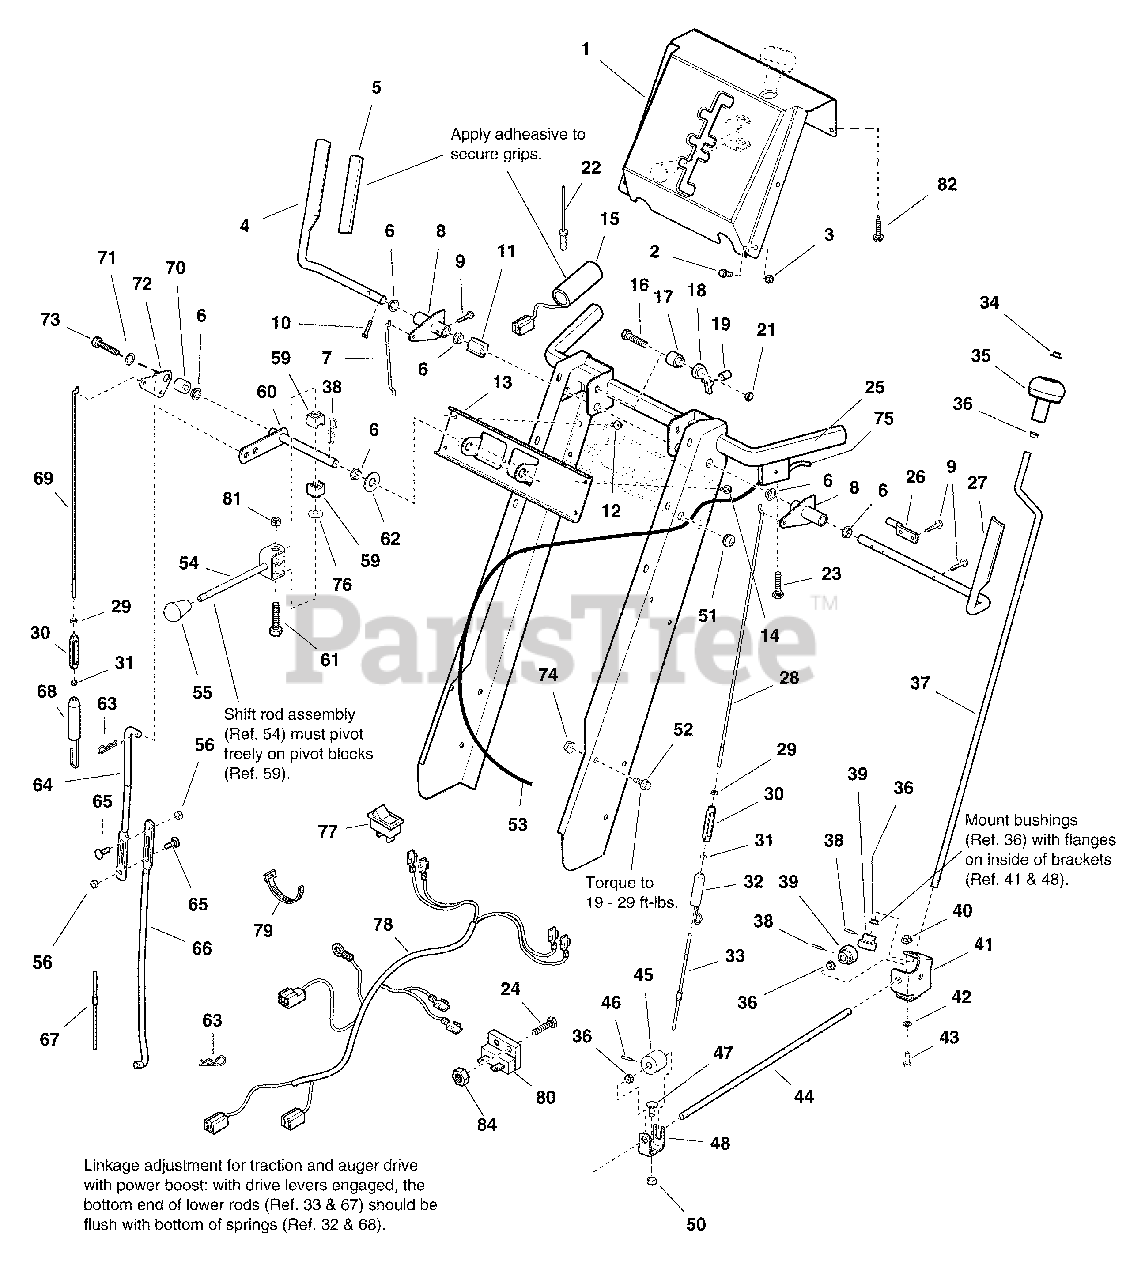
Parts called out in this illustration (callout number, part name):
2	CAPSCREW, Hex Head, 1/4-20 x 3/4
3	NUT, Whiz Lock 1/4-20
4	HANDLE, Clutch, RH
6	BUSHING, Nylon
7	ROD, Clutch
8	LEVER & TUBE ASSEMBLY
9	CAPSCREW, Hex Washer Head, #12-24 x 1
10	CAPSCREW, Hex Washer Head, #10-24 x 1
11	GUIDE, Control
12	SCREW, Hex Washer Head Taptite 1/4-20 x 3/4
13	BRACKET, Shift Control
14	SCREW, Hex Washer Head Taptite 1/4-20 x 3/4
15	HAND GRIP, Heated
16	SCREW, Hex Whiz Lock Flange 5/16-18 x 1 1/2, Black
17	SPACER
18	LATCH, Control
19	SPRING, Compression
21	NUT, Hex ESNA 5/16-18, Black
23	SCREW, Pan Torx Head, #10 x 1/2
24	CAPSCREW, Hex Head, 1/4-20 x 3/4
25	HANDLE ASSEMBLY
26	ROD, Control
27	HANDLE, Clutch, LH
28	ROD, 17.3" Long
29	NUT, LH, Machine Screw, Hex, #10-24
31	NUT, RH, Machine Screw, Hex, #10-24
33	ROD, Clutch
34	PUSH NUT
35	KNOB, Spinner
36	BUSHING, Nylon
37	ROD, Chute Control
38	PIN, Hair
40	NUT, Hex Flange, 1/4-20
41	SUPPORT, Gear
42	PUSH NUT
43	CARRIAGE BOLT, 1/4-20 x 5/8
46	PIN, Spring, 1/8 x 3/4
47	CARRIAGE BOLT, 5/16-18 x 3/4
48	SUPPORT, Worm
50	NUT, Hex ESNA, 5/16-18, Black
52	CAPSCREW, Hex Whiz Lock, 5/16-18 x 3/4
53	CABLE & HANDLE ASSEMBLY, Clutch (Includes Ref. 75)
54	SHIFT ASSEMBLY, Rod & Clevis
56	NUT, Hex KEPS, 1/4-20, Black
59	BLOCK, Pivot
60	ROD & ARM ASSEMBLY, Pivot
61	CAPSCREW, Hex Head, 1/4-20 x 2 1/4, Black
62	WASHER, 1/2
63	PIN, Hair
64	ROD, Shift, Upper
65	CARRIAGE BOLT, 1/4-20 x 3/4
66	ROD, Shift, Lower
67	ROD, Clutch, Lower
69	ROD, Clutch, Upper
71	WASHER, Plain 11/32 x 3/4 x 1/16
72	LEVER, Clutch
73	CAPSCREW, Hex Whiz Lock Flange 5/16-18 x 1 1/2
74	NUT, Hex Flange, 5/16-18
75	TRIGGER ASSEMBLY, Easy Turn Clutch Cable
76	WASHER, Curved, 1/2
77	SWITCH, Heated Grips, Rocker
78	HARNESS, Wiring
79	TIE, Self Locking
80	RESISTOR BLOCK
81	NUT, Hex Flange 1/4-20 ESNA, Yellow
82	SCREW, Hex Washer Head Taptite 1/4-20 x 3/4
84	NUT, Hex Flang ESNA Black 1/4-20
